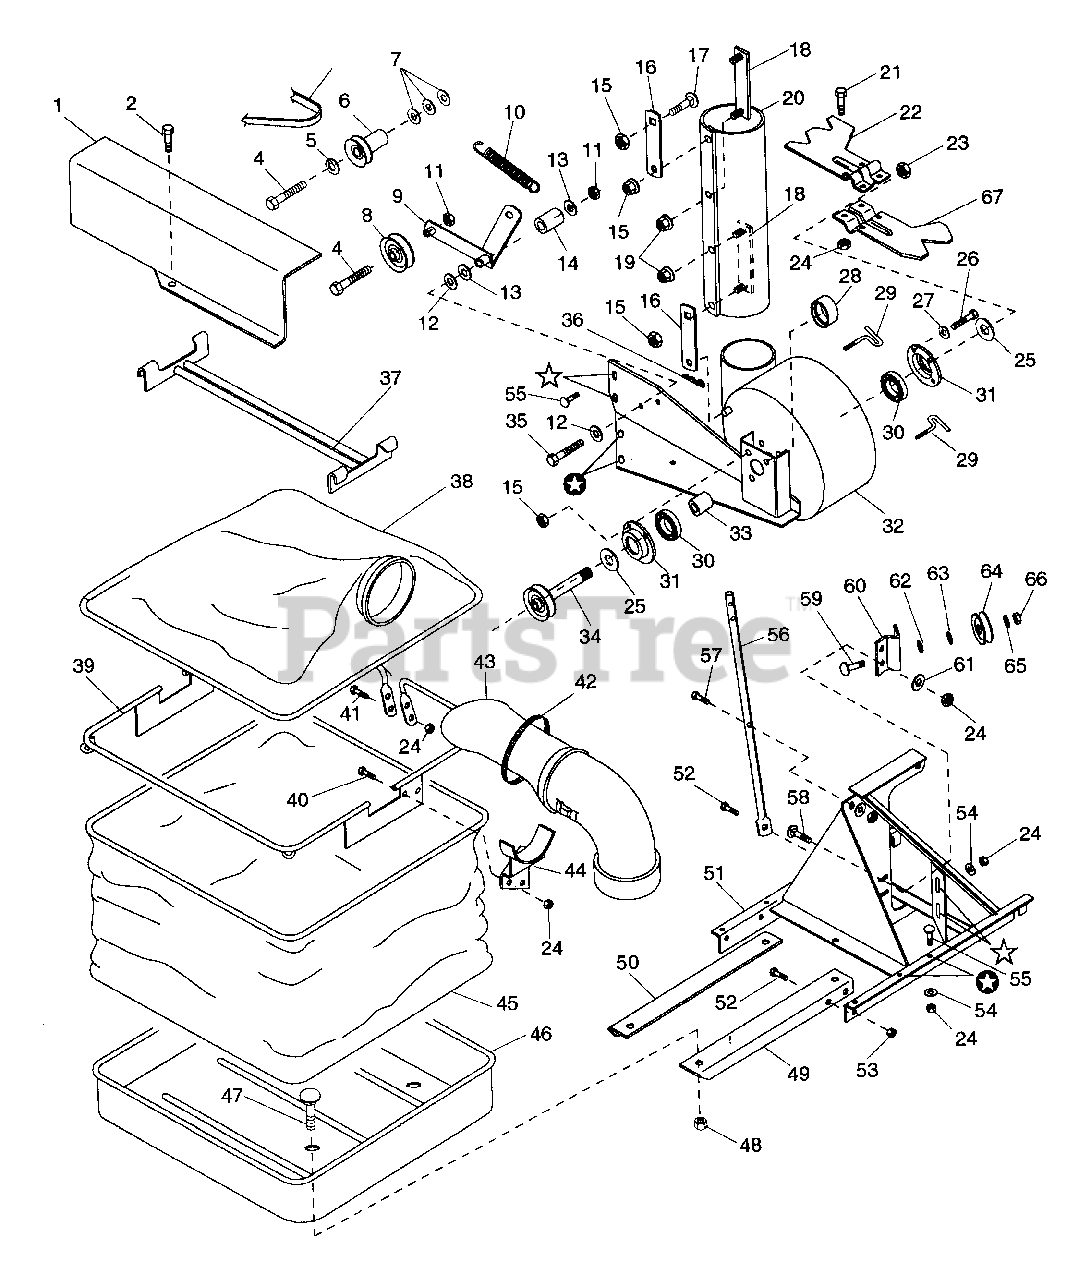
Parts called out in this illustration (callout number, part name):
1	BELT SHIELD
2	SCR-TAP .250-20X.37 HWH PL TR
3	V-BELT, HA-RAW EDGE
4	BLT-HEX .38-16X2.50 PL GR5
5	WSHR-LK .375X.115 HVY PL
6	VAC PTO PULLEY
7	SPACER-SPECIAL CONICAL
8	IDLER-FLAT 2.75 X .38 DAYCO
9	IDLER ARM WELDMENT
10	SG-TENS .135X.98X6.0 WLD 62
11	NUT-LK TOP .375-16 GR C YWZC
12	WSHR-FL-STL .390X.875X.18 PL
13	WSHR-FL-STL .38X.875X.083 PL
14	SPACER .391X.625X1.520
15	NUT-LK TOP .250-20 PL
17	BLT-RDHDSQNK .25-20X.50 SHT PL
19	NUT-LK-FLG .250-20 PL
20	TUBE, UPPER
21	BLT-HEX .31-18X.63 PL GR 2
22	FAN BLADE
23	NUT-LK-JAM 1.0-14 PL
24	NUT-LK .312-18 GR A PL
25	WSHR-FL-STL 1.015X1.500X.125
26	BLT-HEX .25-20X2.00 PL GR5
27	WSHR-FL-STL .268X.562X.046 PL
28	HOUSING
29	CLAMP SCREW
30	BRG-BALL 1.0X2.0X.56 (1641)
31	BEARING FLANGE
32	FAN HOUSING W/ DECAL
33	SPACER 1.010X1.250X.924
34	SPINDLE WELDMENT
35	BLT-HEX .38-16X2.75 PL GR5
36	PIN-HAIR INT .08X.18X1.18
37	CENTER BAG SUPPORT
39	SUPPORT, BAG
40	BLT-HEX .31-18X.75 PL GR2
41	BLT-HEX .31-18X2.25 PL GR2
42	CLAMP-HOSE WRM 2.13/8.62X.56
43	UPPER ELBOW
44	BRACKET-ELBOW SUPPORT
46	BAG TRAY
47	BLT-RDHDSQNK .31-18X.75 GR5 PL
48	NUT-FLG. .312-18 PL
49	RIGHT TRAY SUPPORT
50	LEFT TRAY SUPPORT
52	BLT-HEX .38-16X1.00 PL
53	NUT-LK-CTR .375-16 GR A PL
54	WSHR-FL-STL .323X.625X.062 PL
55	BLT-RDHDSQNK .312-18X.62 PL
56	SUPPORT TUBE
57	BLT-HEX .38-16X2.00 PL GR2
58	BLT-RDHDSQNK .31-18X.75 SHT PL
59	BLT-RDHDSQNK .38-16X1.25 SHTPL
60	IDLER MOUNT
61	WSHR-FL-STL.312X.734X.065PL
62	WSHR-FL-STL .390X.750X.125 PL
63	WSHR-FL-STL .520X.810X.033
64	IDLER-V 4.00 X .38 NWHAMSHR
65	WSHR-FL-STL .382X.812X.062
66	NUT-LK-JAM-CTR .375-16 PL
67	FAN BLADE
